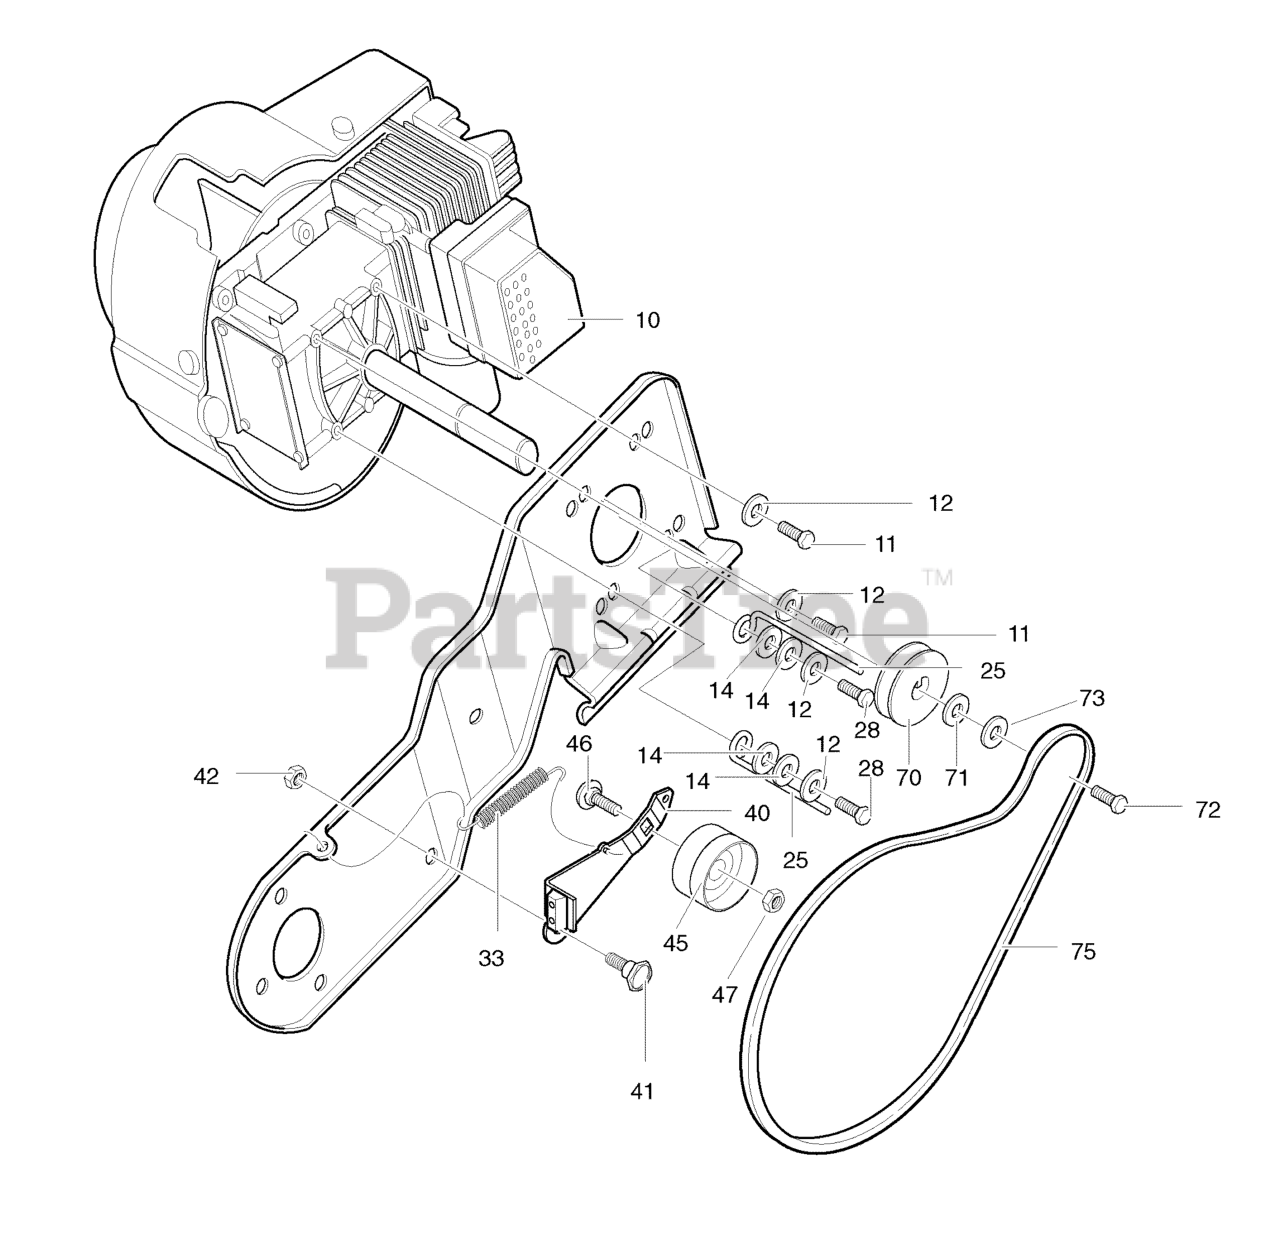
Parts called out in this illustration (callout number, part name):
10	ENGINE
11	SCREW, 5/16-18 x 0.75
12	WASHER
14	WASHER, FLAT
25	GUIDE, BELT
28	SCREW
33	SPRING, IDLER BRAKE
40	ASSY, IDLER BRAKE ARM
42	NUT, 5/16-18
45	PULLEY, IDLER
46	BOLT, CARRIAGE
47	NUT
70	PULLEY, ENGINE
71	WASHER, BELLEVILLE
72	SCREW, 5/16-24 x 0.75
73	WASHER, SPLIT LOCK
75	BELT V 3L 34.8"
